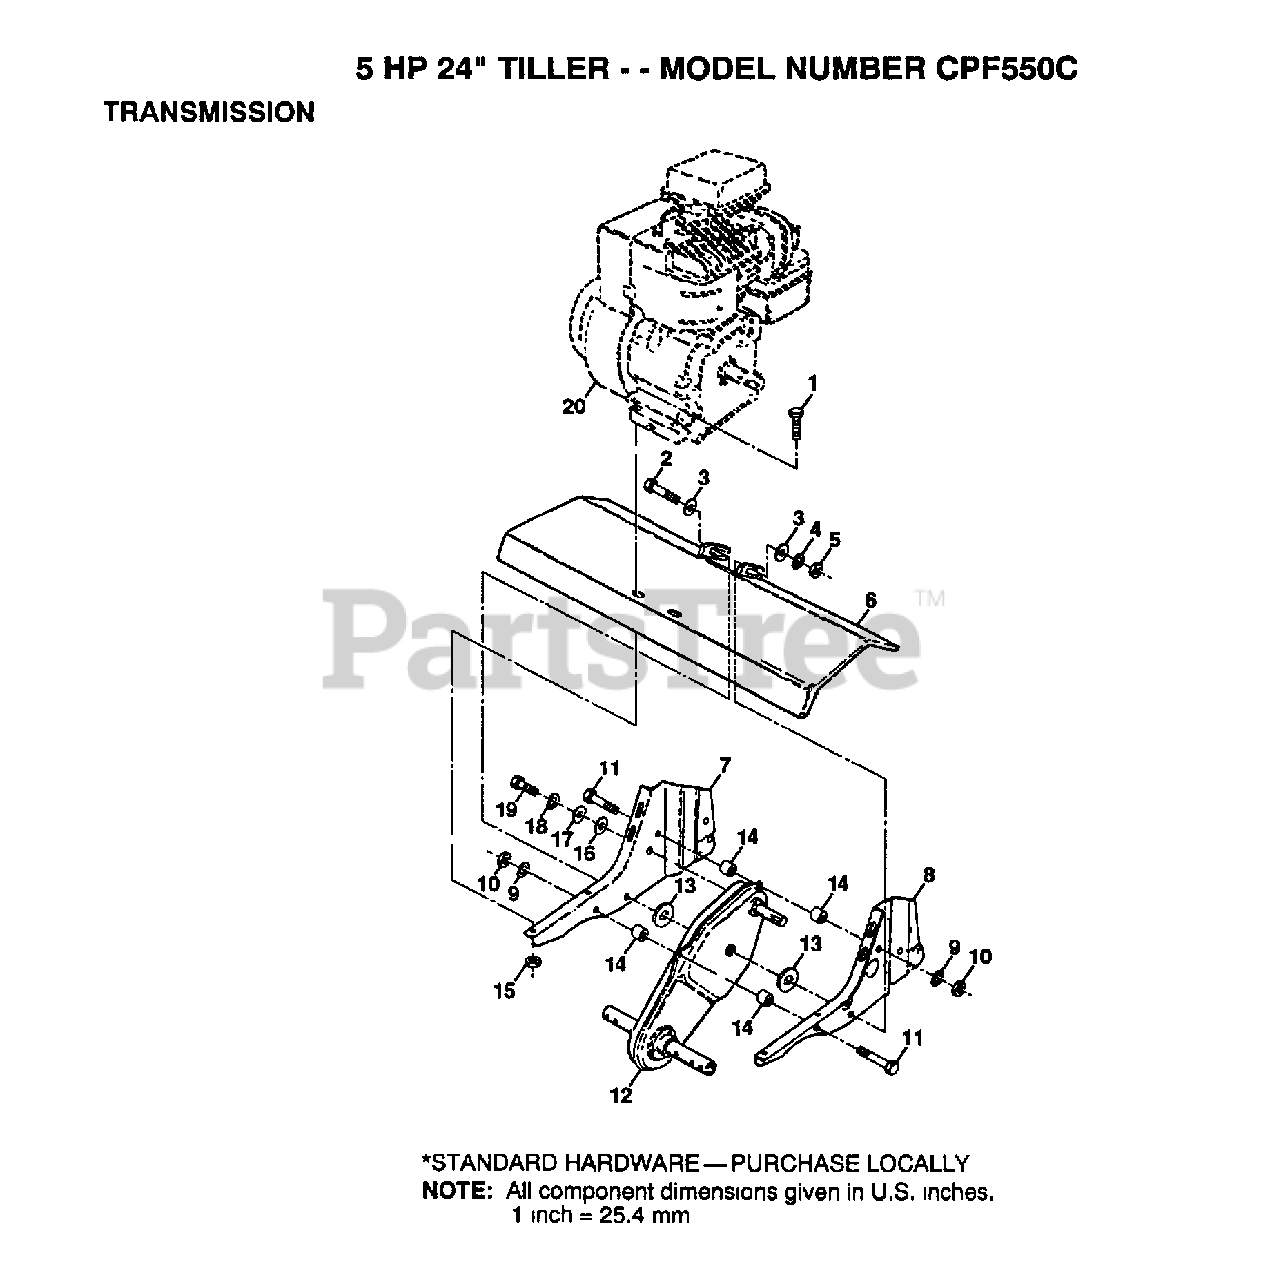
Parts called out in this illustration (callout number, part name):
1	BOLT.HEX.5/16-1.5
2	BOLT.3/8-24X3.75
3	WASHER
4	LOCKWASHER
5	GRIPCO NUT
8	BRACKET.ENG.LH.
9	LOCKWASHER
10	NUT.HEX.5/16-18
14	SPLIT SPACER RT
16	WASHER
17	WASHER
18	LOCKWASHER
19	BOLT
